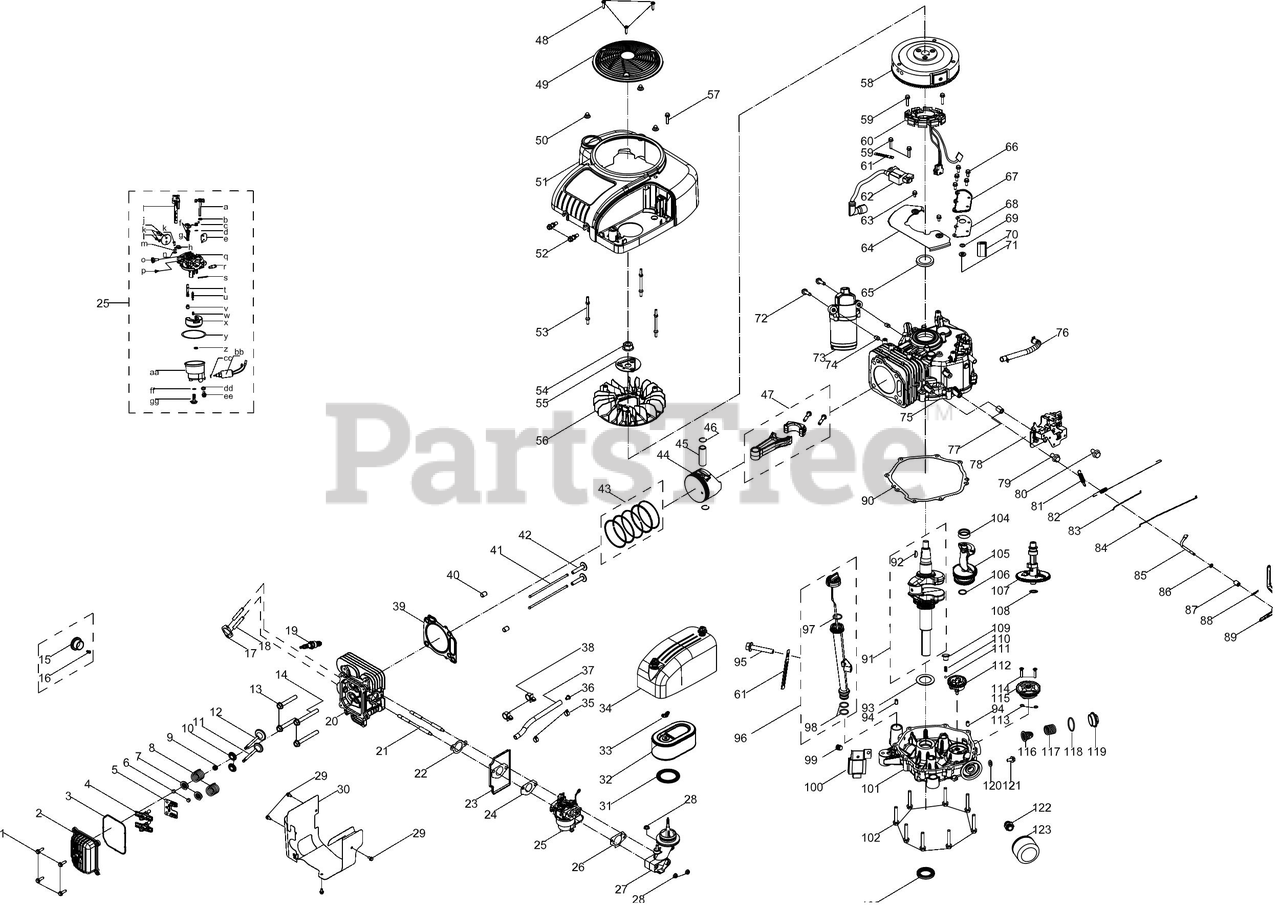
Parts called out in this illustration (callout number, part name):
1	Bolt, M6x22
2	Valve Cover
3	Gasket, Valve Cover
4	Rocker Arm Assembly
5	Rocker Arm Base
6	Valve Adjust Cap, Exhaust
7	Valve Spring Seat
8	Valve Spring
9	Intake Valve Seal
10	Valve Spring Seat
11	Exhaust Valve
12	Intake Vavle
13	Bolt, M10x1.25x65
14	Bolt, M10x1.25x85
15	Spark Arrester
16	Self-tappling Screw, ST5x8
17	Gasket, Muffler
18	Stud, M8x47
19	Spark Plug
20	Cylinder Head
21	Stud, M6-8x140
22	Gasket, Carburetor Insulator
23	Insulator
24	Gasket, Carburetor
25	Carburetor
26	Gasket, Intake Manifold
27	Intake Manifold
28	Nut, M6
29	Bolt, M5x10
30	Shroud
31	Ring,Air Filter
32	Air Filter Assembly
32	Genuine Factory Parts AIR FILTER
33	Butterfly Nut
34	Air Filter Cover
35	Clamp
37	Fuel Hose, 6.3x12.5x290
38	Clip
39	Gasket, Cylinder Head
40	Pin, 12x16
41	Push Rod
42	Tappet
43	Piston Ring Set
44	Piston
45	Piston Pin
46	Circlip
47	Connecting Rod Assembly
48	Self-tappling Screw, ST5.5x25
49	Shroud
50	Nut,M6
53	Stud, M6
54	Nut, M16x1.5
55	Cooling Fan Plate
56	Cooling Fan
57	Bolt, M6x16
58	Flywheel
59	Bolt, M6x28
60	Charging Coil
61	FLEXIBLE CLAMP
62	Ignition Module
63	Bolt, M6x10
64	Shield
65	Oil Seal, 35x52x7
66	Bolt, M6x14
67	Breather Cover
68	Gasket, Breather Cover
69	Breather Valve
70	Breather Filter Screen
71	Second Air Valve Seat
72	Bolt, M8x40
73	Electric Starter
74	Pin, 10x14
75	Crankcase
76	Breather Hose
77	Bush, 6.5x15x20
78	Governor Gear Bracket Assembly
79	Bolt, M6x38
80	Bolt, M6x18
81	Governor Spring
82	Idle Spring
83	Choke Lever
84	Throttle Linkage
85	Governor Gear Shaft
86	Washer, 6x1x12
87	GOVERNOR SEAL
88	Cotter Pin
89	Governor Lever
90	Gasket, Crankcase
91	Crankshaft
92	Woodruff Key
93	Washer, 35.4x2x54
94	Pin, 8x14
95	Bolt, M6x35
96	Dipstick Assembly
97	O-Ring, 21.9x2.62
98	O-Ring, 21.2x2.8
99	ENGINE PLUG 3/8 NPT
100	Regulator
101	Crankcase Cover
102	Bolt, M8x54
103	Oil Seal, 35x52x7
104	Bearing, 6202
105	Balance Shaft
106	Washer, 15.4x1x25
107	Camshaft
108	Washer, 16.4x1x24
110	Spring
111	Ball S6.35
112	Governor Gear
113	O-Ring, 10x2.65
115	Oil Pump
116	Breather Filter Screen
117	Breather Spring
118	O-Ring, 35.5x2.65
119	Breather Cover
120	Washer, 8.3x1.5x17
121	Bolt, M8x15
122	Connection Pipe
123	Oil Filter
123	Cub Cadet OIL FILTER
123	Genuine Factory Parts OIL FILTER
